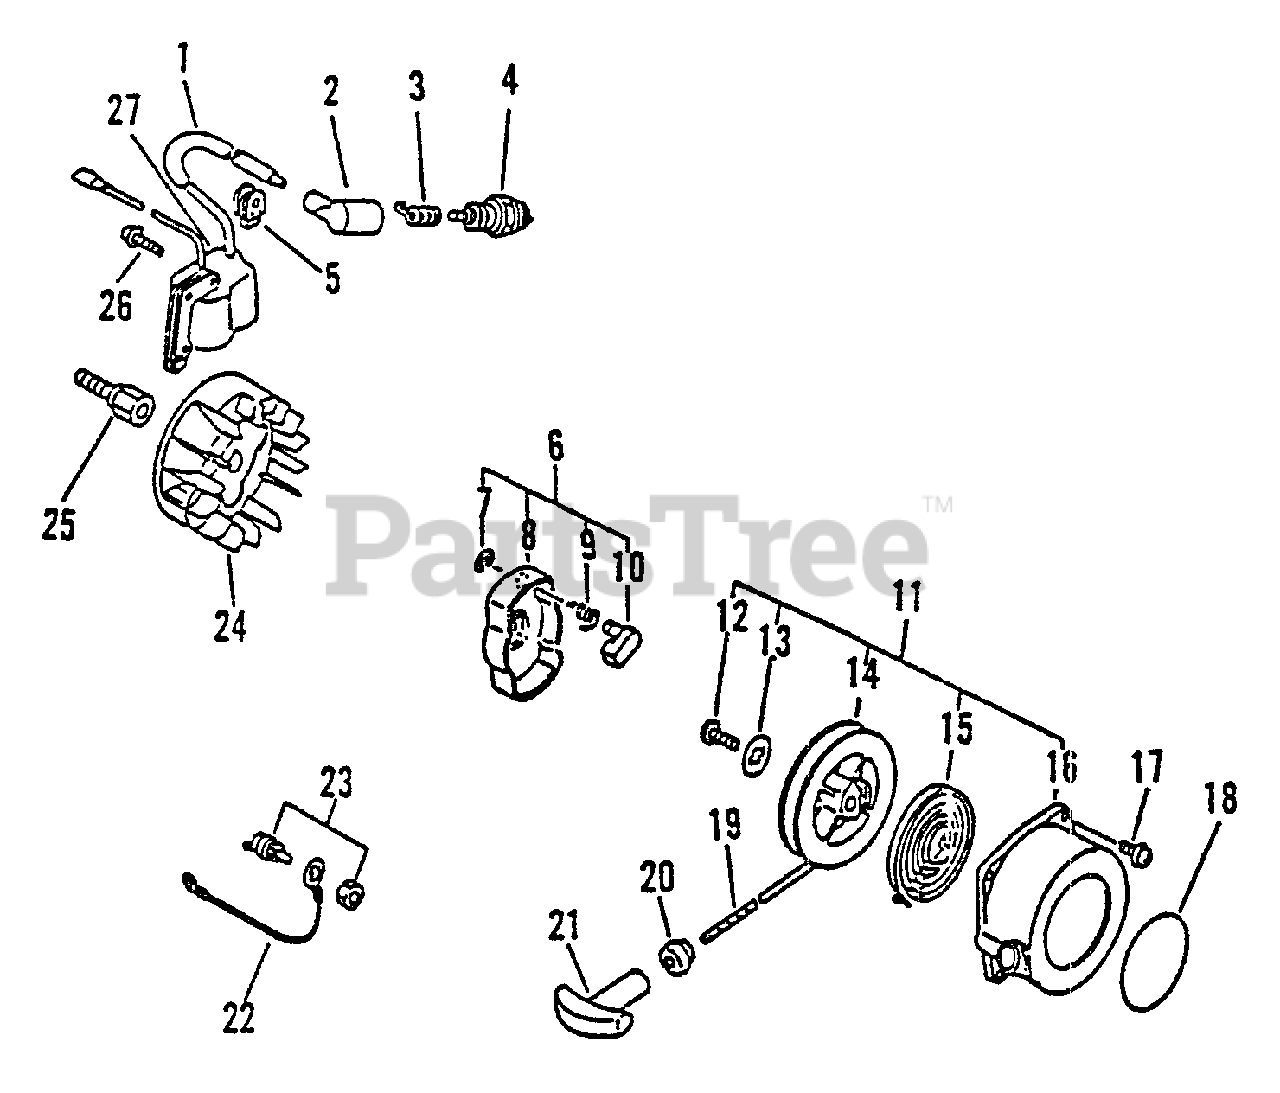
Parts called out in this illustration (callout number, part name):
2	CAP, SPARK PLUG
3	TERMINAL, SPARK PLUG
4	SPARK PLUG - BPM7A
6	STARTER PAWL ASSY
7	E-RING 4
8	CATCHER, PAWL
9	SPRING, RETURN
10	PAWL, STARTER
11	STARTER ASSY
13	WASHER
14	REEL, ROPE
15	SPRING, RECOIL
16	CASE, RECOIL STARTER
17	SCREW 4×18
19	ROPE, STARTER
20	GUIDE, ROPE
21	GRIP, STARTER
22	LEAD - GROUND
23	SWITCH, ON-OFF
24	FLYWHEEL
25	HUB, FAN
26	SCREW 4×22
27	COIL, IGNITION
